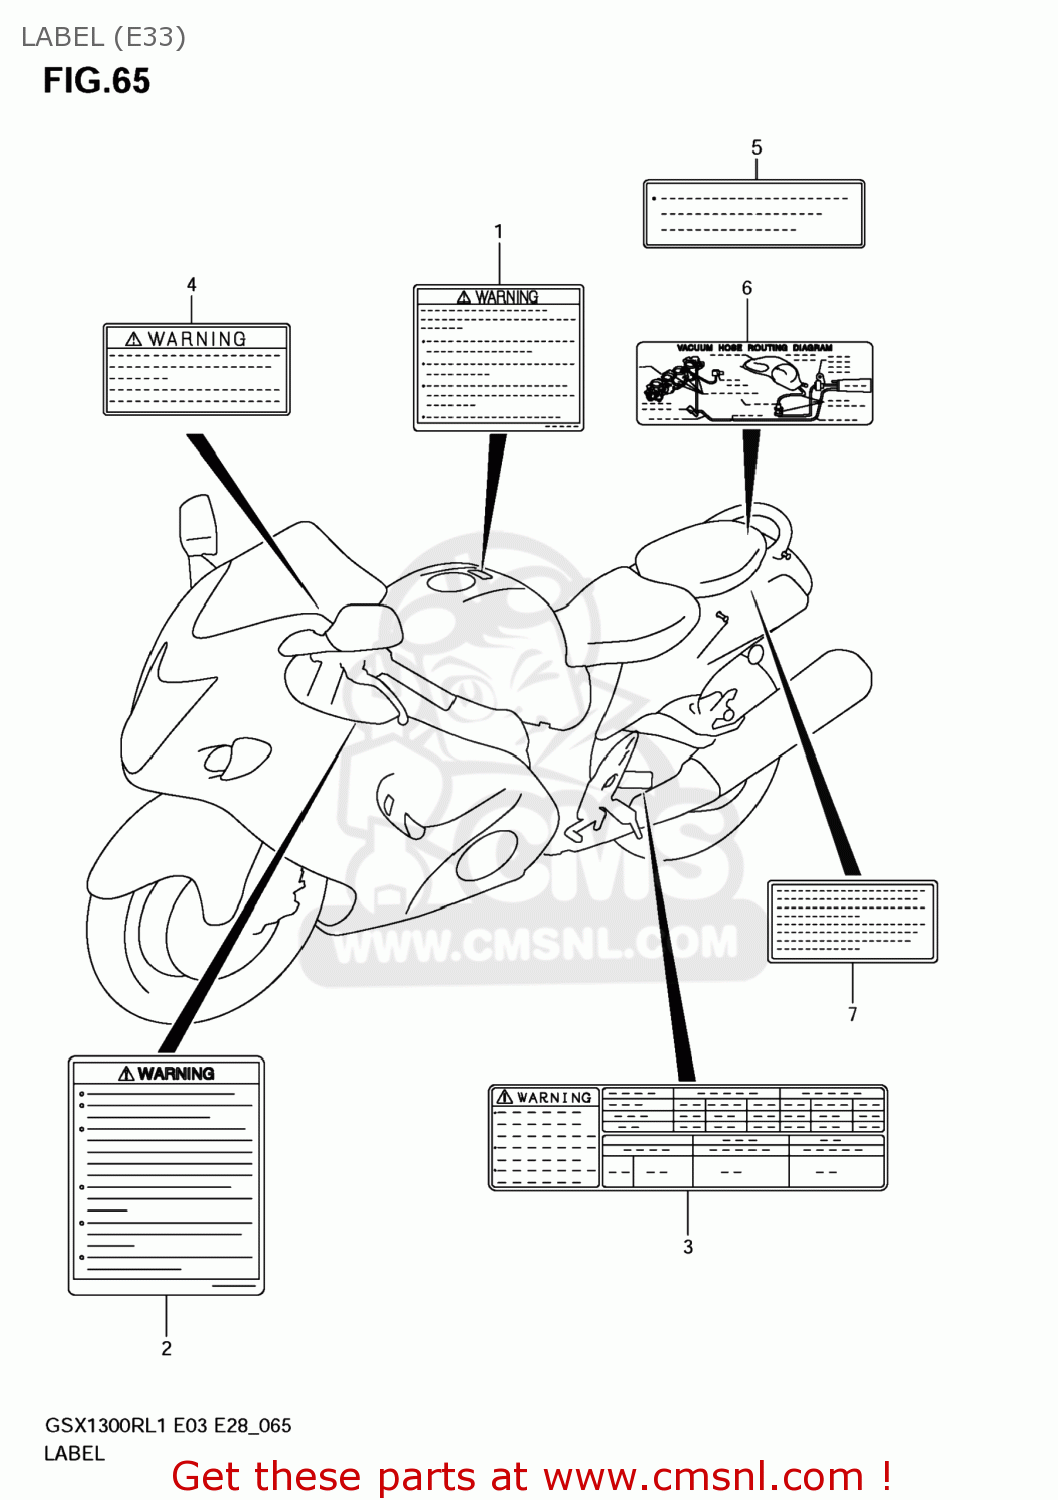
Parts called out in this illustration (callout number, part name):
1	LABEL,GENERAL WARNING
2	LABEL,SCREEN
3	LABEL,TIRE INFORMATION
4	LABEL,WARNING STEERING
5	LABEL,FUEL INFORMATION
6	LABEL,VACUUM HOSE ROUTING
7	LABEL,MANUAL NOTICE
8	MANUAL,SAFETY
9	MANUAL,OWNER'S
